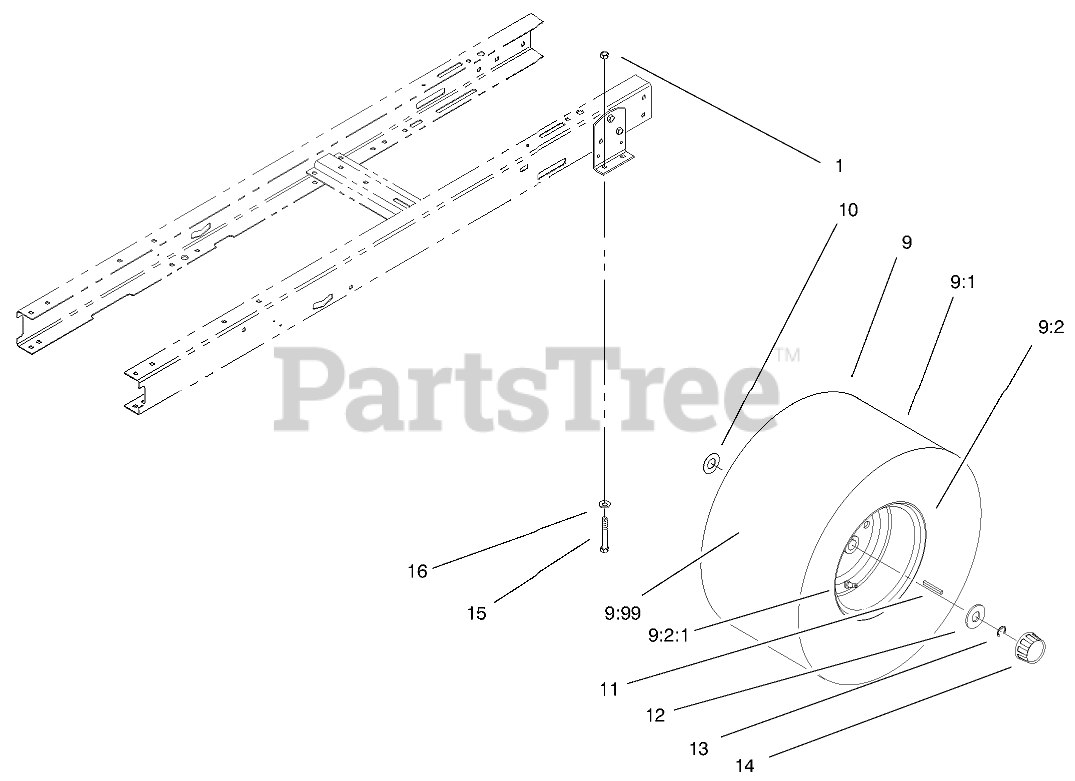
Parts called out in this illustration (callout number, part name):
1	NUT-LOCK, NI
9	Wheel & tire ASM,Rear
9:1	TIRE
9:2:1	STEM-VALVE
9:99	Tube
10	WASHER-THRUST
11	KEY-SQUARE
12	WASHER-PLAIN
13	E-RING
14	CAP-HUB
15	SCREW-HH
16	WASHER-PLAIN
